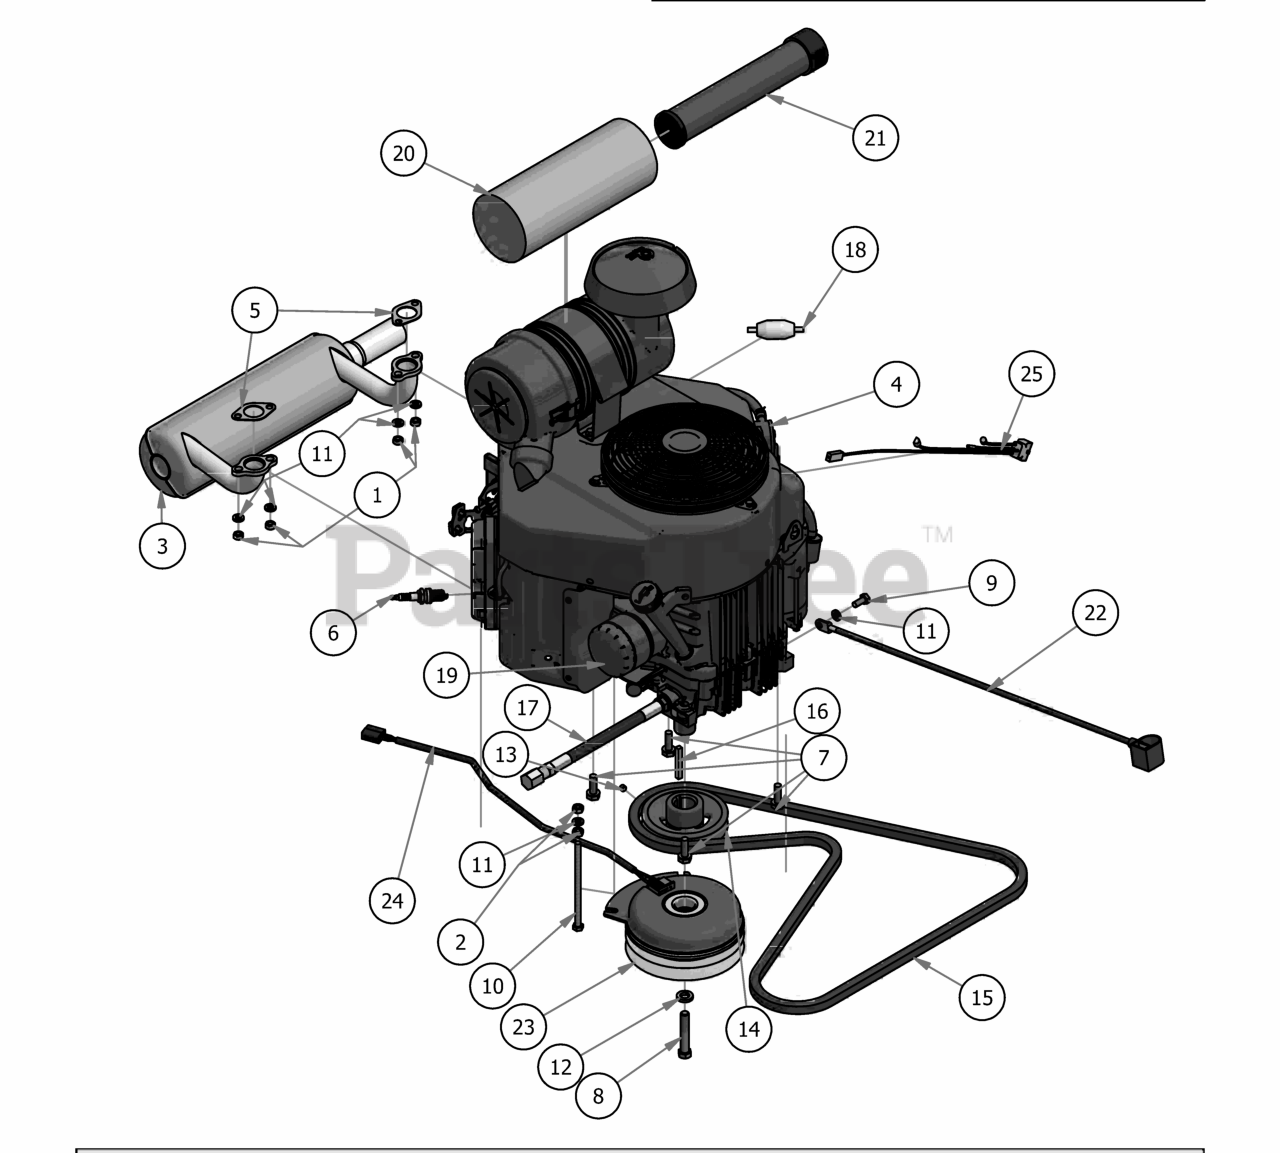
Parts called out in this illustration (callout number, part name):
1	M8-1.25 Zinc Nut
3	Kawasaki Muffler 1251
4	Kawaski FX-691V Engine
5	Exhaust Gasket
6	Spark Plug - Kawasaki
7	3/8 x 1 1/8 bolt
8	7/16" x 2 1/2" Hex Bolt
9	M8x1.20x20MM Hex head bolt
10	5/16-18 x 5-1/2 GR 5 Hex Bolt
11	5/16" Lock Washer
12	7/16" Lock Washer
13	5/16 Set Screw
14	4 3/4 Motor Pulley
16	1/4 x 2 Square key Stock
17	Oil drain Hose
18	Universal Inline Fuel Filter
19	Oil Filter
20	Canister Air Filter- Outer
21	Canister Air Filter- Inner
22	24" Black Ground Cable
23	Clutch Assembly
24	Clutch Pigtail
25	Harness Adaptor
26	Jumper Wire (Not Picured)
